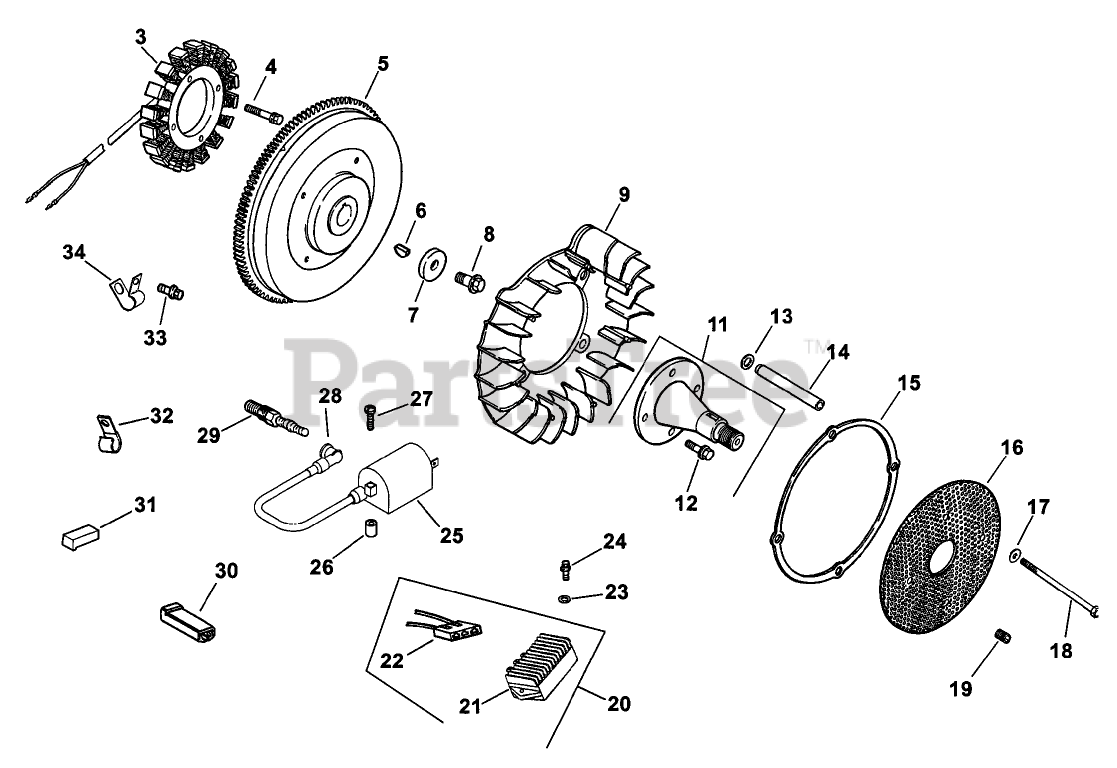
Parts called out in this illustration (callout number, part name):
3	Stator
4	Screw-Cap, Hex (M5x0.8x30)
5	Flywheel
6	KEY (3/16 X 5/8)
7	WASHER-FLAT (13/32)
8	SCREW-FLANGE (M10X1.5X45)
9	Fan
11	Kit-Shaft, Front Drive(Incl. Ref.# 12)
12	Screw-HF (M8x1.25x25)
13	Washer-Spring (10MM)
14	Spacer
15	Ring-Support
16	Screen-Grass
17	WASHER-FLAT (1/4)
18	Screw-HH (M6x1.0x100)
19	Screw-Set (10-24X.25)
20	Kit-Conversion, FullWave (Incl. Ref.#22,25 452 01-S &24 518 12-S)
21	Rectifier-Regulator
22	Connector (3 contact)
23	WASHER-FLAT (.188)
24	SCREW-PHL HD (11-16X.88)
25	Coil-Ignition
26	Spacer
27	Screw-Phillips
28	Spark Plug Boot ASM
29	Spark Plug
31	Connector
32	Clip-Cable
33	SCREW-FLANGE, THREAD FORMING (M5X0.8X16)
34	Clamp-Hose
